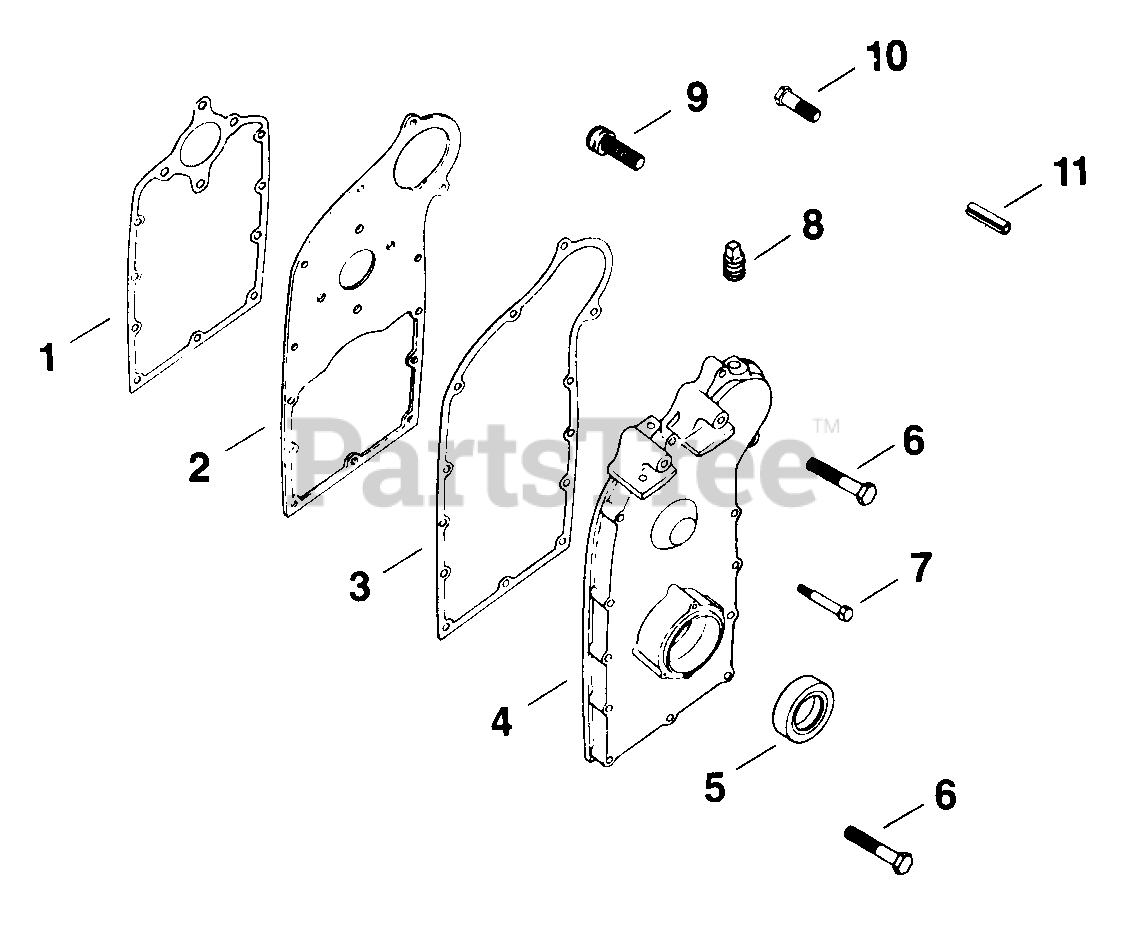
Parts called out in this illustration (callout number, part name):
2	PLATE - (#DSC)
5	SEAL, OIL (KM)-USE 25 032 06-S
6	SCREW, CAP HD 5/16-18x1 3/4"- (#DSC)
7	SCREW - (#DSC)
8	PLUG,PIPE 1/4 NPTF SQUARE HD USE 25 139 53-S
9	SCREW, HEX SOCKET HEAD CAP USE 25 086 87-S
10	SCREW, CAP HD 5/16-18x3/4"
